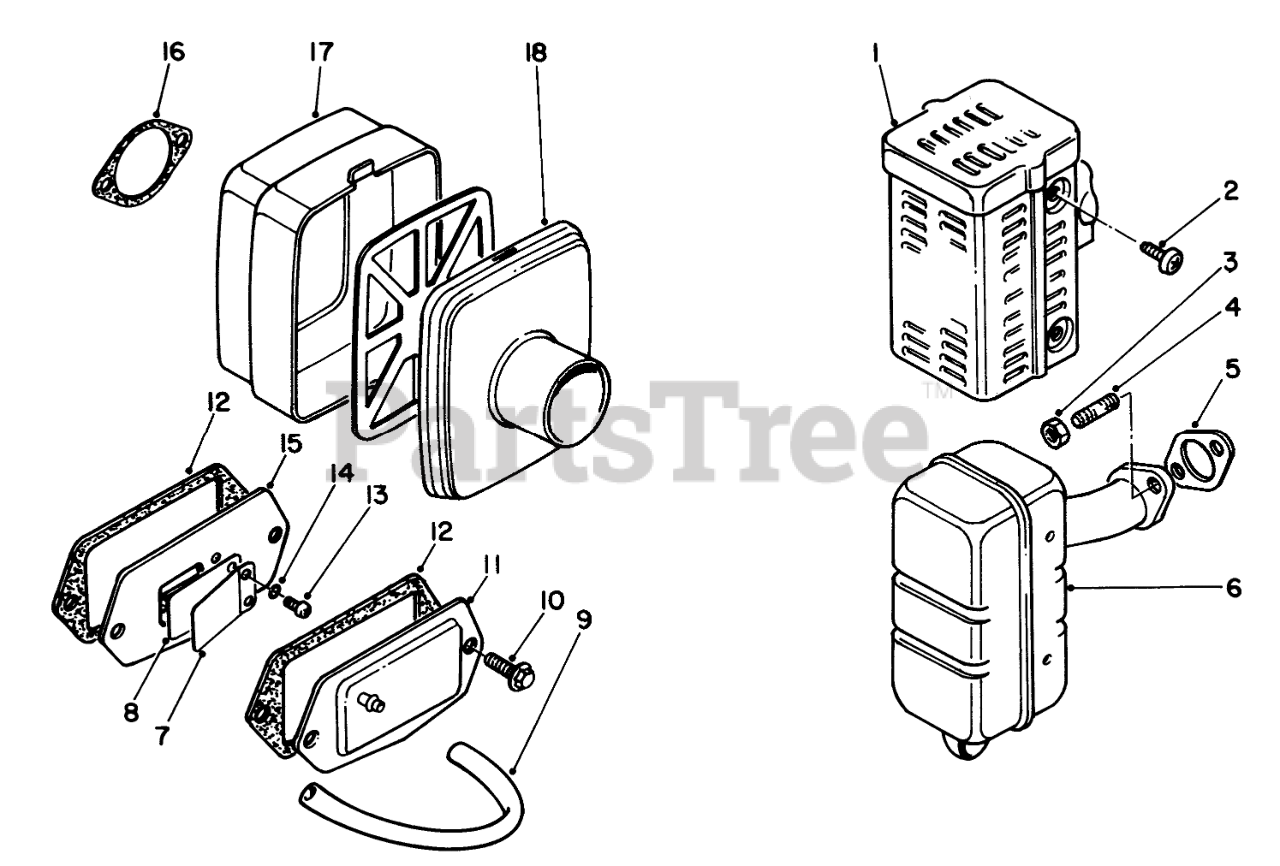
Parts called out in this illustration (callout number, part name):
1	Cover-Muffler
2	Screw-Round Phillips Hd.
4	Stud Bolt
5	Gasket-Exhaust
6	Muffler
7	Stopper
8	Reed Valve
11	Cap-Breather
12	Gasket
13	Screw
14	Lockwasher
15	Reed Valve Assembly (Incl. Ref. #7, 8, 13 & 14)
16	GASKET-AIR CLEANER
17	Air Cleaner Assembly (Incl. Ref. #18)
